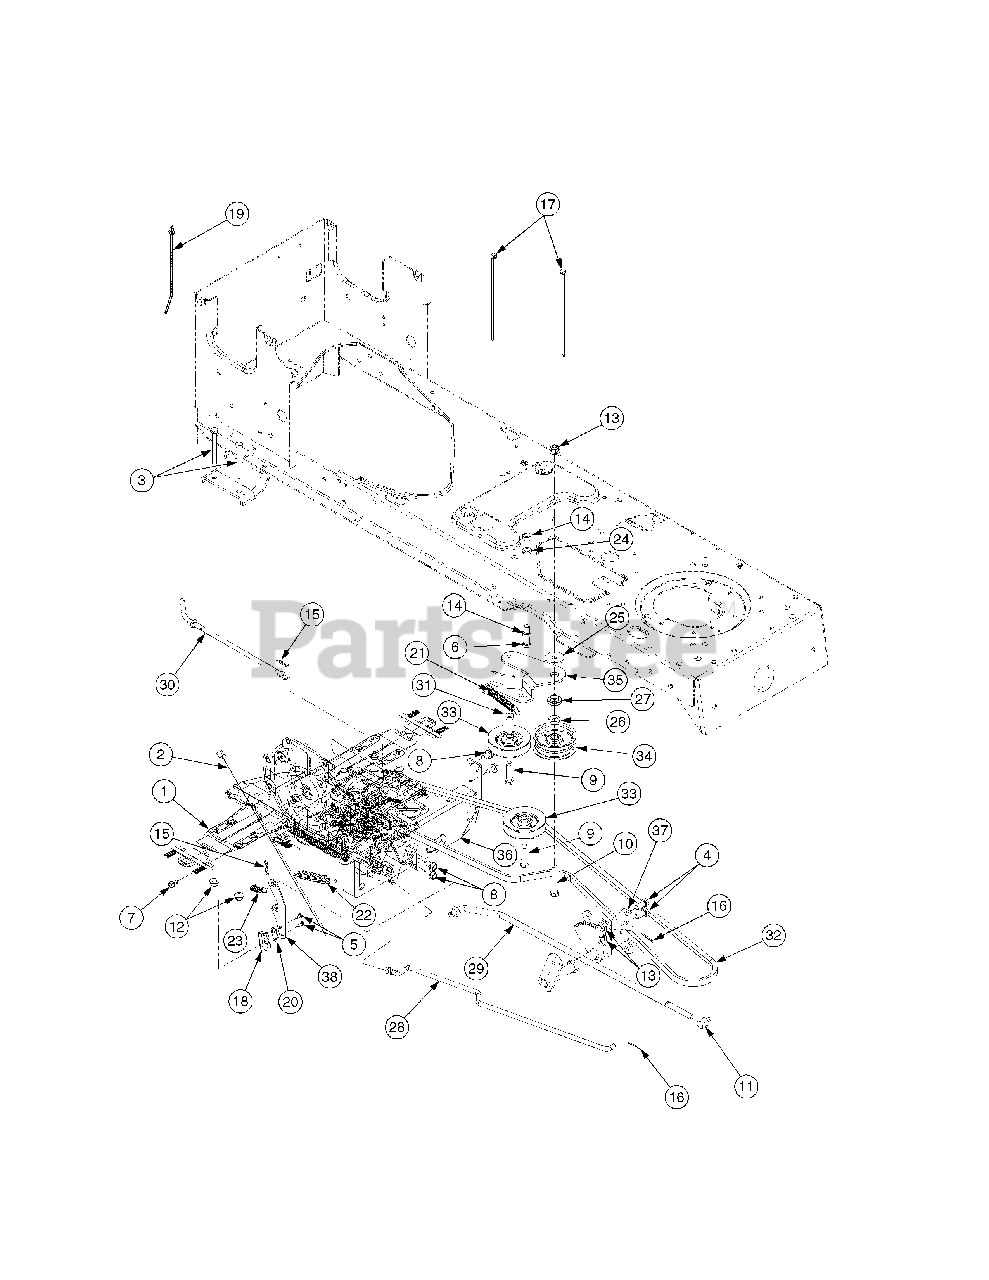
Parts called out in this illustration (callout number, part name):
1	Transmission, Hydro
2	Harness, Rev
3	Screw, Hex Cap, 5/16-18 x 2.75 GR5
4	Screw, Hex Cap, 3/8-16 x .75 GR5
5	Screw, Hex Wash Hd Tapp, #8-18 x .5
6	Hex Cap Screw, 3/8-16 x 1.5, GR5
7	Screw, Hx Wash Hd Tapp, 1/4-20 x .5
8	Screw, Hx Wash Hd Tapp, 5/16-12 x .75
9	Screw, Hx Wash Hd Sems Tapp 3/8-16 x 1.5
10	Hex Cap Screw, 3/8-16 x 2.25, Gr5
11	Ferrule, 3/8-24 x .375 Dia
12	Nut, Flange Insert Lock, 5/16-18 Gr5
13	Nut, Flange Insert Lock, 3/8-16 GrF
14	Nut, Hex, 3/8-16, GR5
15	Pin, Cotter, .072 Dia. x 1.13 Lg
16	Pin, Cotter, 3/32, 1.0
17	Cable, Tie, 3/16 x .05 x 7.4
18	Switch, Spring, Short
19	Tie, Cable, Push Mount 7.5 Lg
20	Plate, Insulator Nut
21	Spring, Extension, .50 Dia x 3.97 Lg
22	Spring, Extension, .59 OD x 4.00 Lg
23	Spring, Extension, 3/8 OD x 1.44 Lg
24	Washer, Lock, 3/8 , Regular Duty
25	Washer, Flat, .38 x 1.38 x .125
26	Washer, Flat, .407 x .812 x .135 Hdn
27	Spacer, Shoulder, 1.00 x .38 x .38
28	Rod, Brake, LT
29	Rod, Hydro Control
30	Rod, Hydro Disengage
31	Spacer, .376 ID x .625 OD x .22
32	Belt, V Type A, 79.10 Lg
33	Pulley, Idler, V Type x 3.06 Dia
34	Pulley, Idler, Flat 2.75 OD
